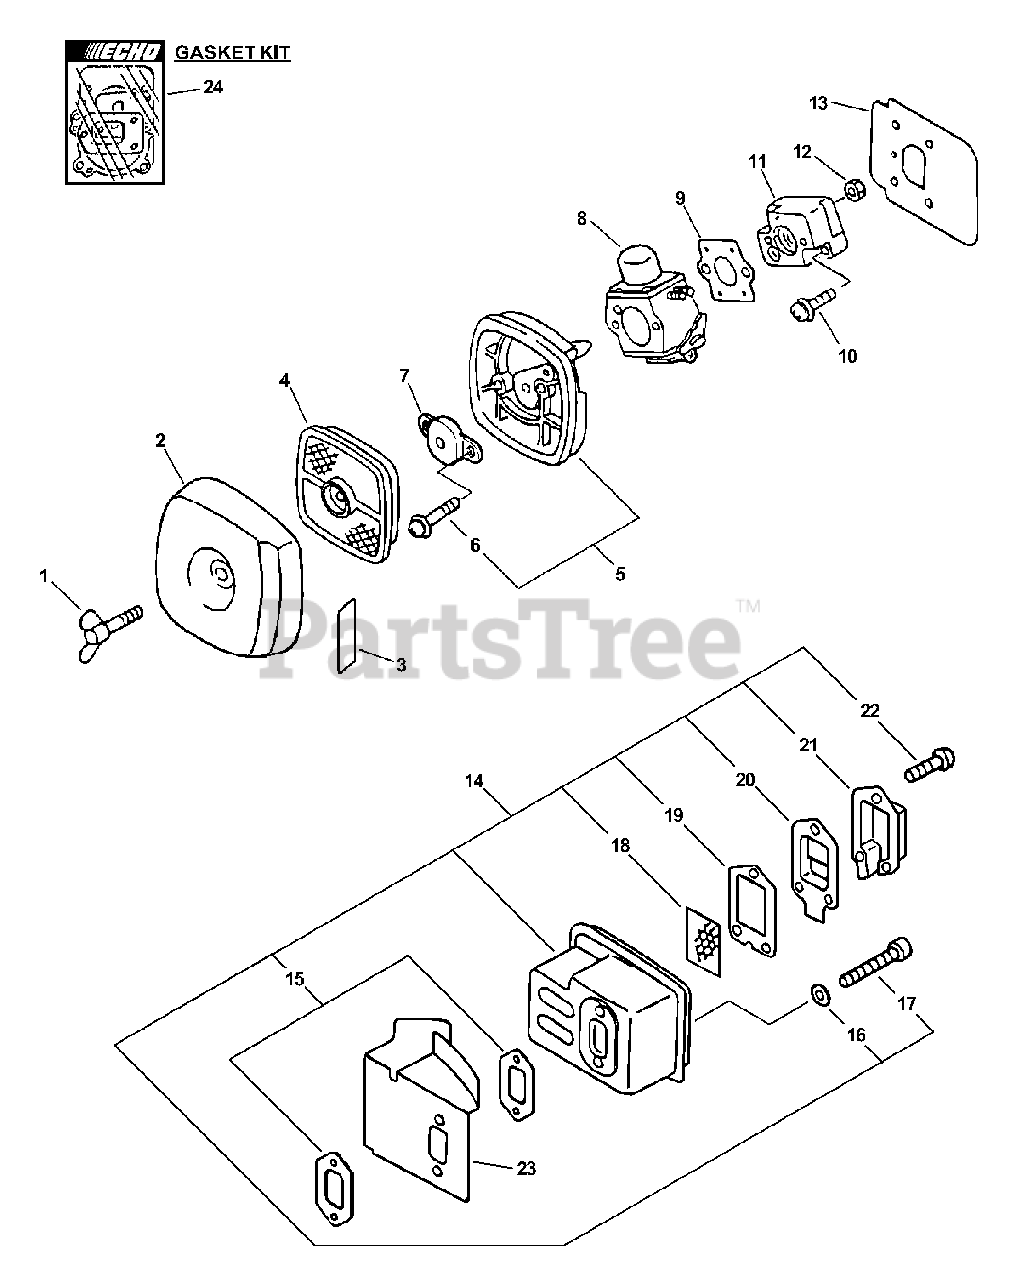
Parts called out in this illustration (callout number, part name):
1	THUMBSCREW
2	COVER, AIR FILTER - GRAY
3	LABEL - CHOKE
4	FILTER, AIR - SINGLE LAYER
5	AIR FILTER CASE KIT - GRAY
6	SCREW - 5X65
7	PLATE, PREVENT
8	CARBURETOR C1U-K54
9	GASKET, INTAKE
10	SCREW - 5X20
11	INSULATOR, INTAKE
13	SHIELD, INTAKE
14	MUFFLER ASSY
15	GASKET, EXHAUST
16	WASHER - 5
17	SCREW - 5X50
18	SCREEN, SPARK ARRESTOR
19	GASKET, EXHAUST
20	GASKET, EXHAUST - INNER
21	GUIDE, EXHAUST - OUTER
22	SCREW - 4X10
23	SHIELD, EXHAUST
24	GASKET KIT
